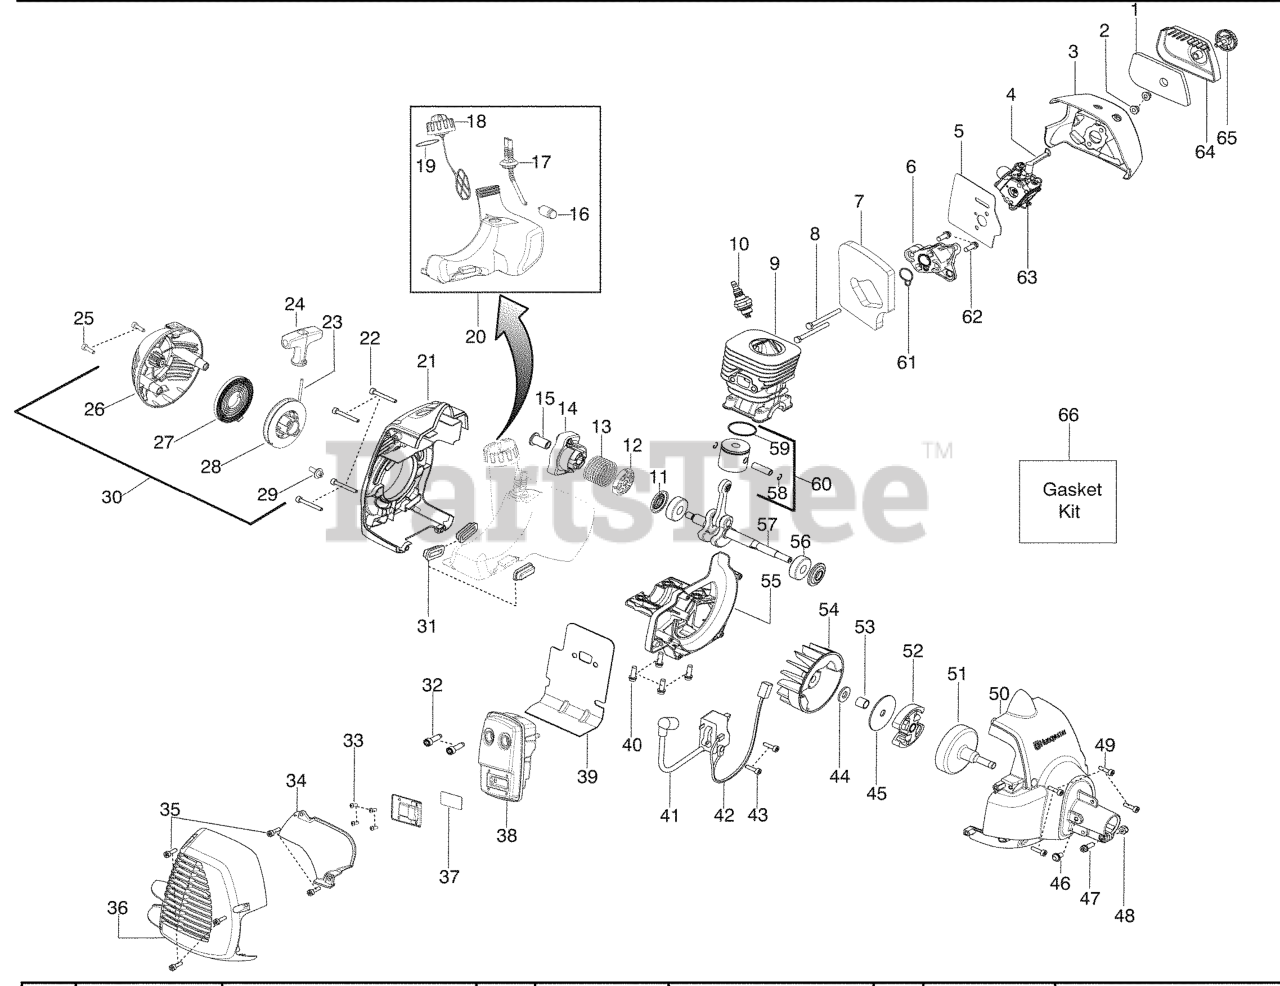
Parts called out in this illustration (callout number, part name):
1	FILTER AIRBOX
3	Air Box
4	CHOKE LEVER
5	KIT GASKET CARB
6	CARB ADAPTOR
7	KIT GASKET 28CC
8	BOLT CARB ADAPTOR
9	CYLINDER
10	Plug-Spark (RCJ-8Y)
11	KIT SEAL CRANKSHAFT
12	WASHER STARTER
13	SPRING STARTER CUP
14	ASSY STARTER CUP
15	COUPLING STARTER
16	FUEL PICK-UP ASSY
17	KIT FUEL LINE
18	ASSY-CAP W/RETAINER
19	KIT GASKET 28CC
20	FUEL TANK ASSY
21	REAR SHROUD
24	STARTER HANDLE GRAY
25	Screw
26	STARTER HOUSING
27	%KIT STARTER SPRING
28	KIT STARTER PULLEY
30	ASSY-STARTER HSG.
31	ISOLATOR FUEL TANK
32	BOLT MUFFLER
33	SCREW-10-16 X 1/2 HI-LO
34	SHIELD HEAT
35	SCREW M4 X 1.75 PT 16MM
36	GUARD-MUFFLER
37	KIT SPARK ARRESTOR SCREEN
38	ASSY-MUFFLER
39	KIT GASKET 28CC
40	SCREW-M5-0.8 X 25MM(TAP)
41	IGNITION MODULE MBU-7
42	ASSY MODULE LEAD WIRE
43	SCREW M4 X .70 TT 16MM
44	WASHER CLUTCH
45	WASHER-CLUTCH
48	LOCKNUT-HEX 10-24
49	SCREW M4 X .70 TT 16MM
50	FAN HSG ASSY
51	Assy-Clutch Drum
52	%KIT CLUTCH ASSY
53	SPACER FLYWHEEL
55	Crankcase
56	BEARING RADIAL BALL (6201)
57	KIT CRANKSHAFT ASSY
58	WRIST PIN RET.
59	RING PISTON
60	KIT PISTON 28CC TRIMMER
61	KIT GASKET 28CC
62	SCREW-M5-0.8 X 25MM(TAP)
63	Kit-Carb.
64	COVER-AIR BOX
65	KNOB ASSY AIRBOX COVER
66	KIT GASKET 28CC
